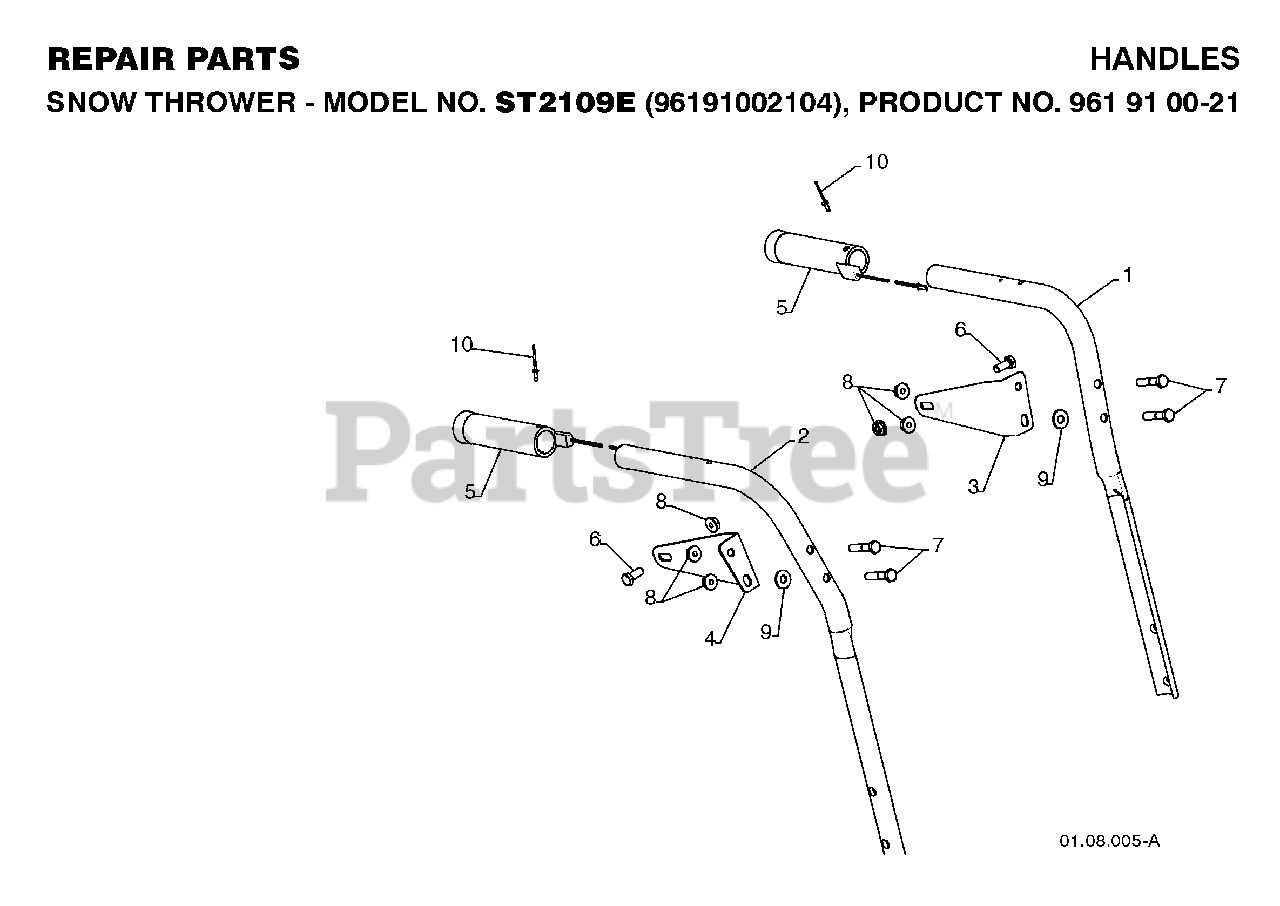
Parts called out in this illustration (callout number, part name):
1	TUBE.HANDLE.PLOW.LH.BLACK
2	TUBE.HANDLE.PLOW.RH.BLACK
3	BRKT.PANEL.LH.INT
4	BRKT.PANEL.RH.INT
5	GRIP HANDLE HEATED
6	BOLT
7	HEX BOLT
8	NUT, LOCK 5/16-18
9	WASHER.20X8.5
10	RIVET.POP.1/8X
